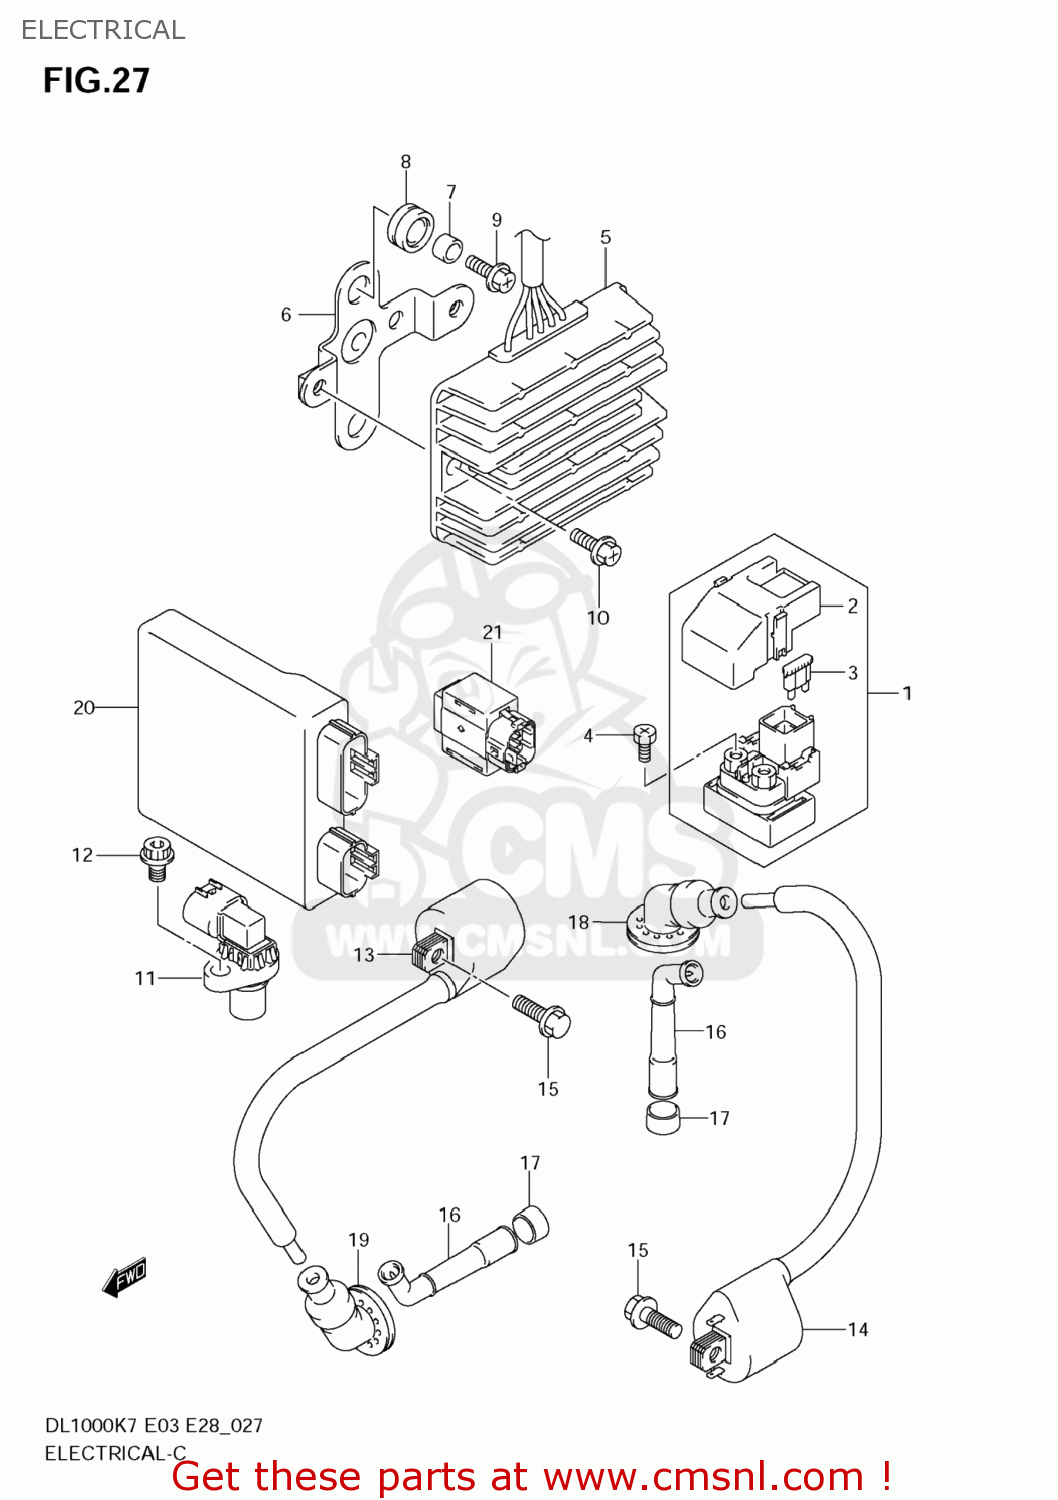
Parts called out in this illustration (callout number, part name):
1	RELAY ASSY,STARTING MOTOR
2	COVER
3	FUSE(30A)
4	SCREW(6X8)
5	RECTIFIER ASSY
6	BRACKET,RECT FTG
7	SPACER(6.5X9X6.7)
8	CUSHION
9	SCREW
10	SCREW
11	SENSOR ASSY,CRANK POSITION
12	BOLT
13	COIL ASSY,IGNITION
14	COIL ASSY,IGNITION
15	BOLT
16	CAP ASSY,SPARK PLUG
17	SEAL,SPARK PLUG
18	SEAL,HIGH TENSION CORD RR
19	SEAL,HIGH TENSION CORD FR
20	CONTROL UNIT, FI (MODEL K4/K5 E33MODEL K6 E3/E28/E33)
21	SENSOR ASSY,FUEL CUT
